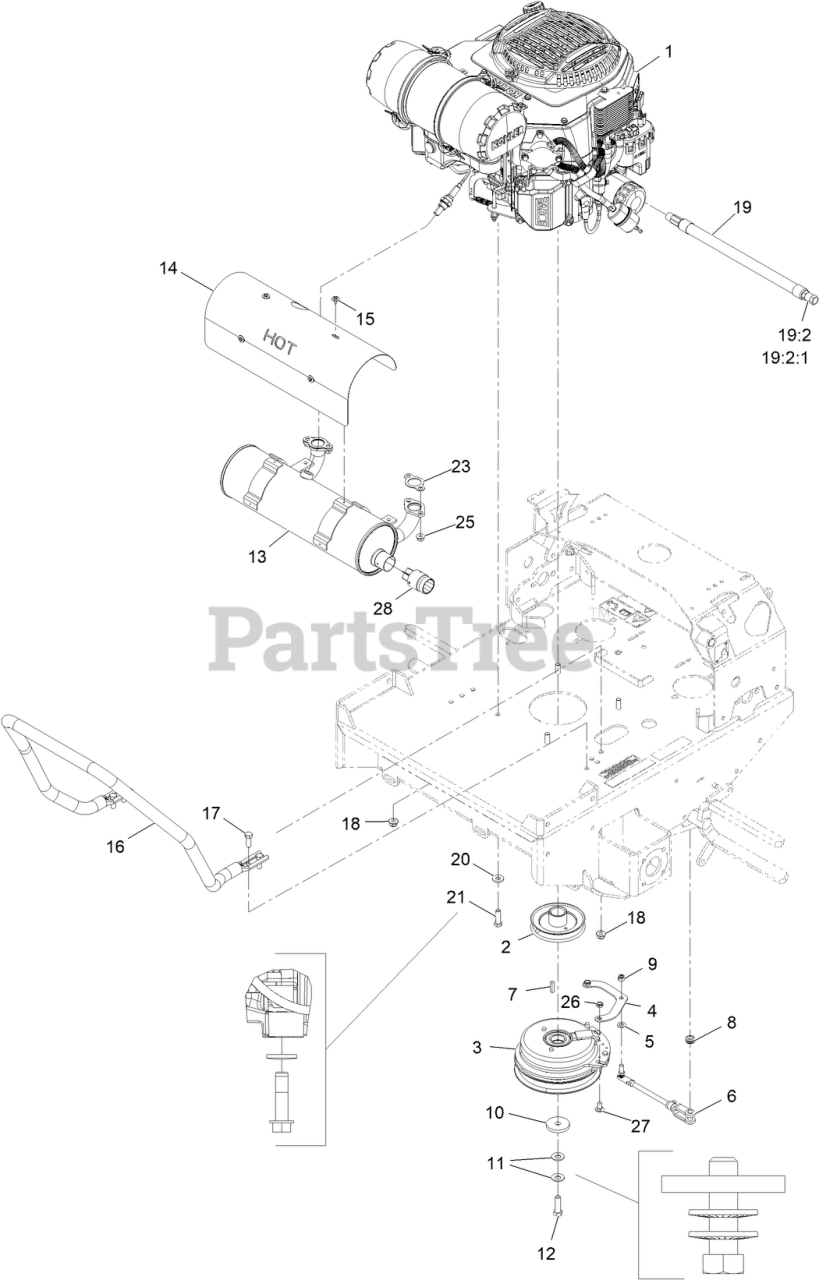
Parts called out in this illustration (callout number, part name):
2	SHEAVE W/ HUB
3	CLUTCH, 200 FT/LBS, 1.13
4	STRAP, CLUTCH
5	WASHER-PLAIN
6	ASM, CLUTCH ANCHOR
7	KEY
8	GROMMET
9	NUT-LOCK
10	WASHER-CLUTCH
11	WASHER-SPRING
12	BOLT-HEX, TAP
13	MUFFLER-TTX, EFI
14	SHIELD-MUFFLER,TTX EFI
15	SCREW-HH, THREAD FORMING
16	TUBE-GUARD AIR CLEANER
17	SCREW-HH
18	NUT-HF, NI
19	OIL DRAIN HOSE ASM
19:2	PLUG-HH
19:2:1	O-RING
20	WASHER-BELLEVILLE
21	SCREW-HWH
23	GASKET-EXHAUST
25	NUT-FLANGE
26	NUT-LOCK, NI
27	SCREW-CARR
28	Screen-Spark Arrestor
